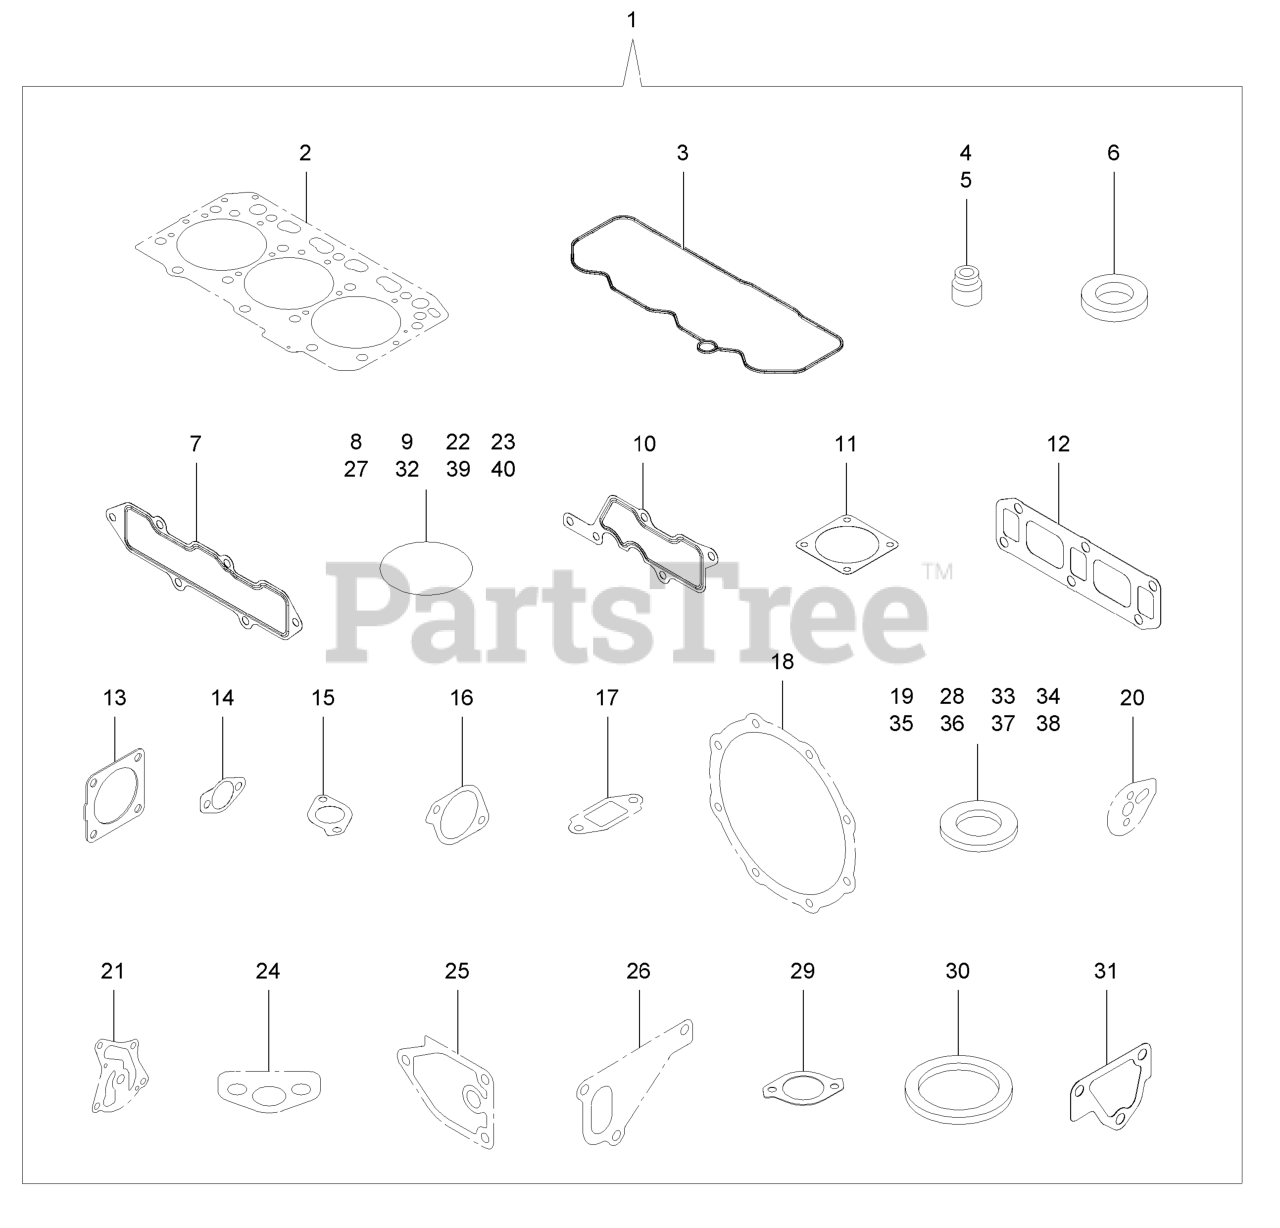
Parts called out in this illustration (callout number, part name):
1	Packing (Gasket Set)
2	Head Gasket ASM
3	Gasket-Head, Cylinder
4	Seal-Stem, Valve
5	Seal-Stem, Valve
6	Gasket-Injector
7	Gasket-Manifold, Intake
8	O Ring-Sensor, Pressure
9	O Ring-Sensor, Temp
10	Gasket-Collector
11	Gasket-Throttle
12	Gasket-Manifold, Exhaust
13	Gasket-Silencer
14	Gasket-Cooler, E G R
16	Gasket-Intake Valve, E G R
17	Gasket-Out Valve, E G R
18	Gasket-D P F
19	Gasket-Sensor
20	Gasket-Idle, Shaft B
32	O Ring-Pump, Fuel
33	Washer-Seal
34	Washer-Seal
35	Washer-Seal
36	Washer-Seal
